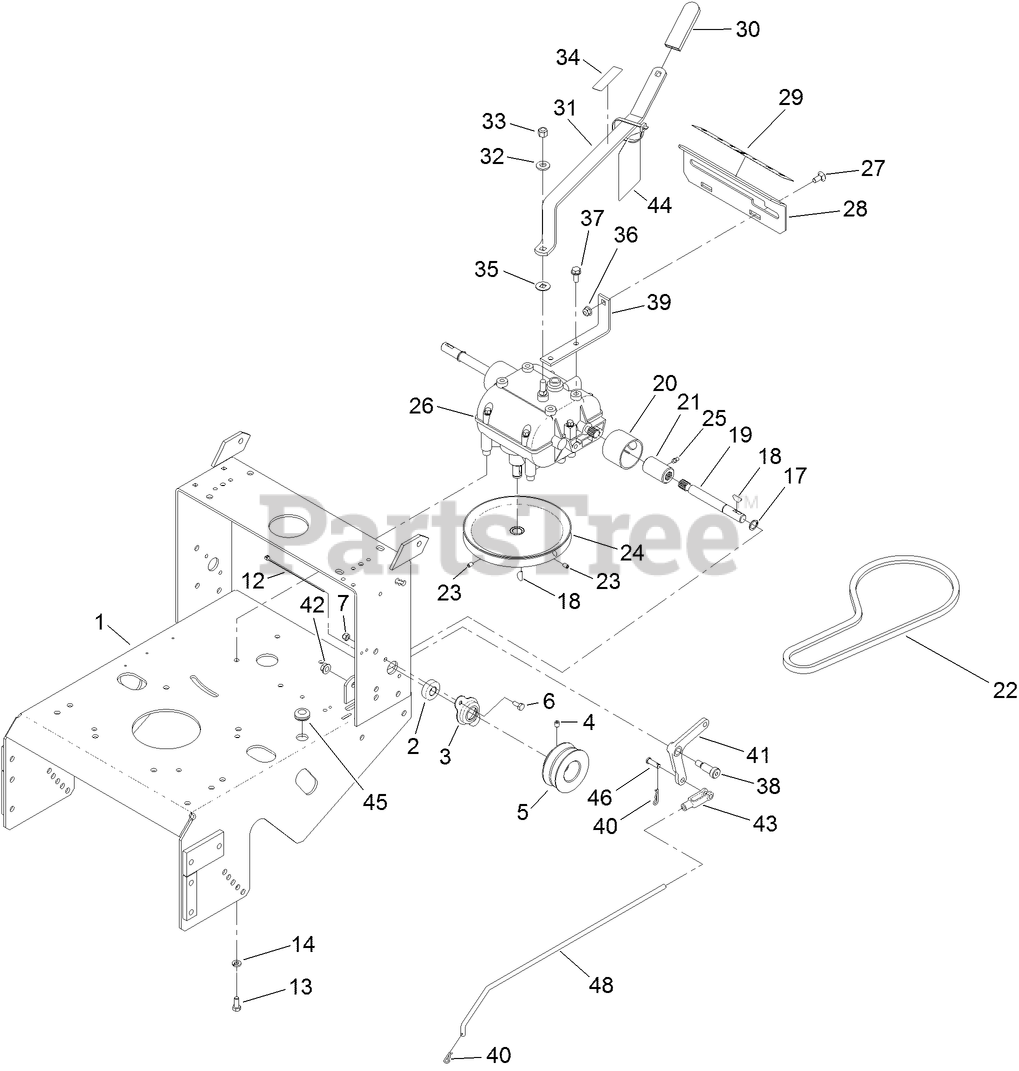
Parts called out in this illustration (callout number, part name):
1	FRAME-GEAR
2	BEARING-SHAFT
3	FLANGE-OUTPUT
4	SETSCREW
5	SHEAVE-TRANSMISSION
6	SCREW-HH
7	NUT-LOCK, NI
12	TIE-CABLE
13	SCREW-HH
14	WASHER-LOCK
17	RING-RETAINING
18	KEY-WOODRUFF
19	SHAFT-TRANSMISSION
20	GUARD-COUPLER
21	COUPLER
22	V-BELT
23	SCREW-HSH
24	SHEAVE-TRANSMISSION
25	FITTING-GREASE
26	TRANSMISSION
27	BOLT-CARR
28	PLATE-SHIFT
29	DECAL-SPEED, GROUND
30	GRIP-LEVER
31	LEVER-SHIFT
32	WASHER-BELLEVILLE
33	NUT-LOCK
34	DECAL-CAUTION, GEARBOX
35	WASHER
36	NUT-HF, NI
37	SCREW-HWHTF
38	BOLT-SHOULDER
39	BRACKET-PLATE, SHIFT
40	PIN-COTTER
41	BELLCRANK
42	NUT-HHF, WHIZ
43	YOKE-ADJUSTABLE
44	HANG TAG-GEARBOX
45	GROMMET
46	PIN-CLEVIS
48	ARM-ASSIST, LINKAGE
